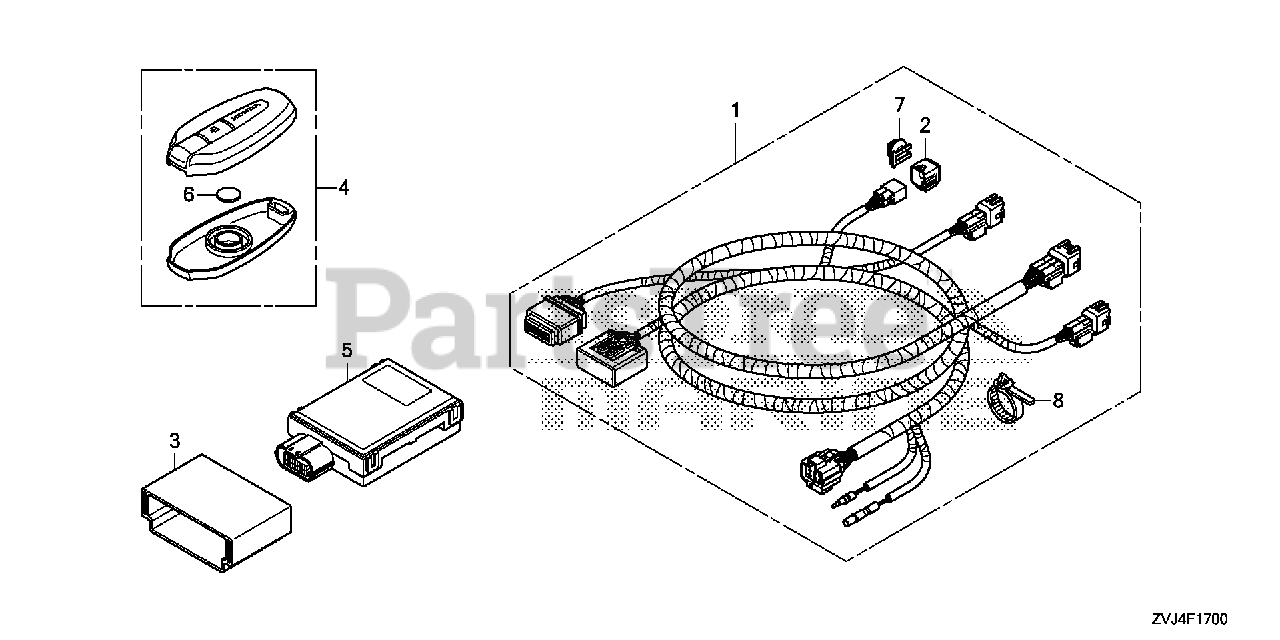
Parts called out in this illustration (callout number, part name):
1	HARNESS ASSY., SMART KEY CONTROL
2	CAP, DUMMY (WPC 4P 090 M) (RED)
3	SUSPENSION, CONTROL UNIT (SMART)
4	FOB ASSY. (315MHZ) (NOT AVAILABLE)
4	FOB ASSY., ENTRY KEY (433.92MHZ)
5	CONTROL UNIT, SMART (315MHZ)
5	CONTROL UNIT, SMART (433.92MHZ)
6	BATTERY (CR2025) (MSDS)
7	CLIP, CONNECTOR (DARK BROWN)
8	CLIP, HARNESS BAND (145MM) (BLACK)
